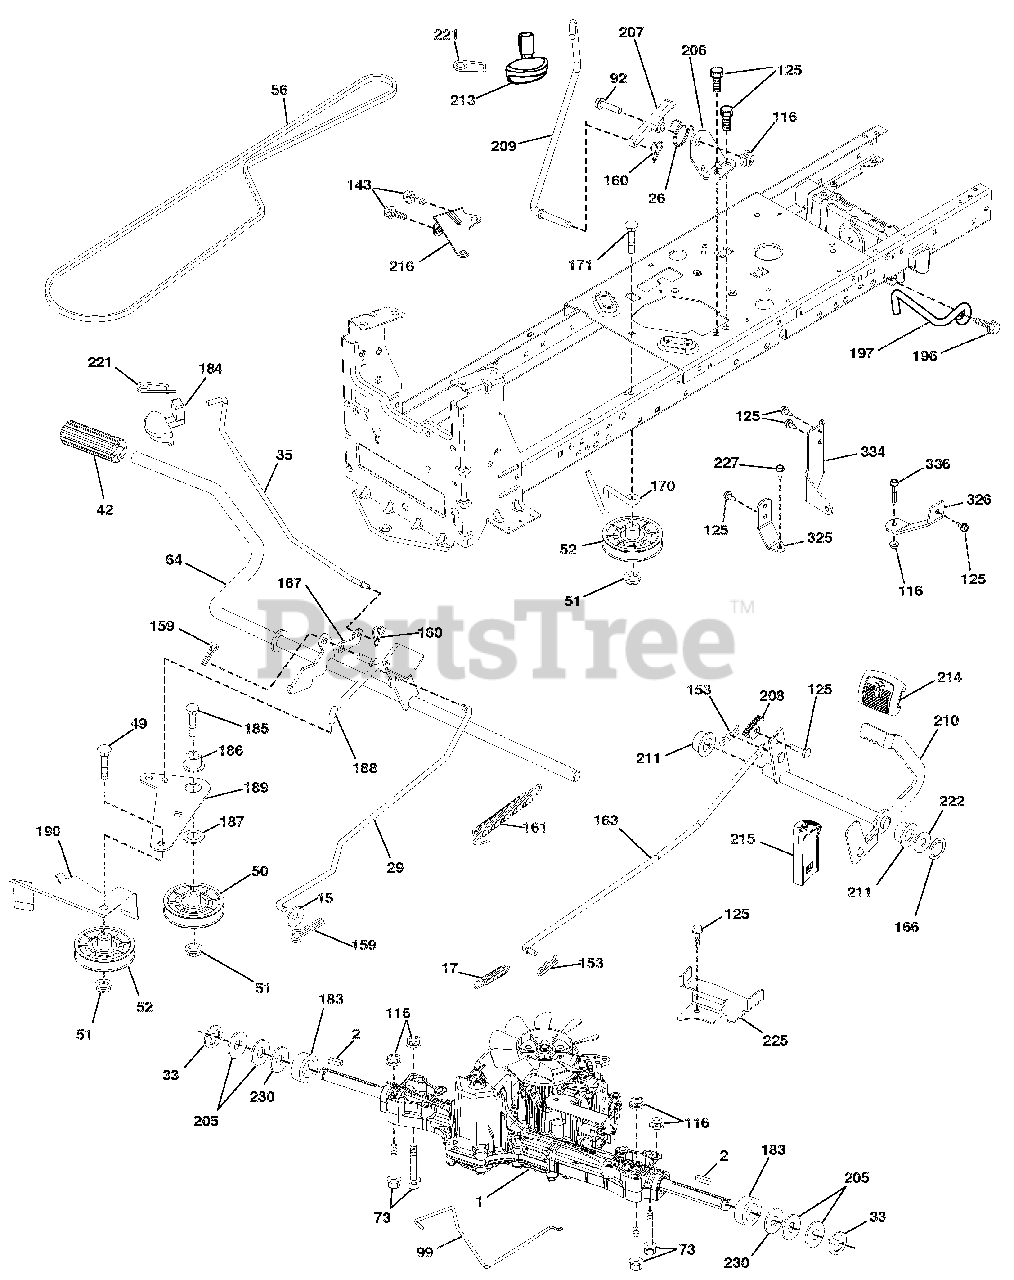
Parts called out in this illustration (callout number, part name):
2	KEY.SQUARE.2.0 X .1845/.1865
15	WASHER.13/32 X 13/16 X 16 GA.
17	SPRING.BRAKE.K46.GREEN
26	SPRING.RETURN.CRUISE
29	ROD.BRAKE.K46
33	E-RING.#5133-75
35	ROD.BRAKE.PARKING.LT.TEX
42	COVER PEDAL BLK ROUND
49	BOLT.RDHD.3/8-16UNCX1-3/4.GR5
50	IDLER.FLAT.910"OFFSET
51	Nut, Hex, Flangelock 3/8-16
52	IDLER.V-GROOVE.910"OFFSET
56	V-BELT.MOWER.92.40.42/K46
64	SHAFT ASM.PEDAL.BRK.CNTRL.PCH
73	BOLT.HEX.FLGHD.5/16-18.GR.5
92	Bolt, Hex Head 5/16-18 x 1-1/4
99	ROD BYPASS
116	Nut, Lock Hex Flange 5/16-18 u
125	SCREW.5/16-18X3/4.SMGML.TAP/BL
143	SCREW.THDROL.5/16-18 X 1/2TYTT
153	RETAINER SPRING
159	PIN.COTTER.1/8 X 3/4.CAD.
160	RETAINER.CLIP(M).DIA.290
161	SPRING.RETURN.CLUTCH.6.75
163	ROD CONTROL
166	NUT PUSH .625
167	LATCH.BRAKE.PARKING
170	KEEPER BELT CENTERSPAN
171	BOLT.RD.HD.SQ.NK.3/8-16UNC X 2
183	SPACER.AXLE.HYDRO/PEERLES
184	HANDLE.PARKNG.BRAKE.LT.TEX.667
185	BOLT.RDHD.3/8-16UNC X2-3/4 GR5
186	SPACER.RETAINER
187	WASHER.13/32 X 2 X 10 GA.
188	LINK.CLUTCH.GROUND DRIVE
189	BELLCRANK.GROUNDRIVE.NSTG/NSTL
190	KEEPER.BELLCRANK.DRIVE.GROUND
196	SCREW.3/8-16X1.SMGML.TAP/R.BLK
197	LINK CLUTCH ANTI-ROTATION
205	WASHER.25/32 X 1-5/8 X 16GA.
206	BRACKET MOUNT LATCH CRUISE
207	LATCH.CONTROL.CRUISE
208	GEAR SECTOR.CONTROL.CRUISE
209	ROD.CONTROL.CRUISE
210	ROCKER ASM.PEDAL CONTROL.TEXLT
211	BEARING.NYLON.BLK..629 ID.
213	KNOB.CONTROL.CRUISE
214	PAD PEDAL FORWARD
215	PEDAL REVERSE
216	BRACKET.PULLEY.IDLER.WTEX
221	RETAINER.SPRING.CLIP.HANDLE
222	WASHER.21/32X1-1/4.10GA.N/PLTD
225	KEEPER.BELT.TRANSAXLE.K46
227	SCREW 5/16-18 X 3/4
230	WASHER.HARDEN..793 X 1.637X060
325	BRACKET
326	BRACKET
334	BRACKET
